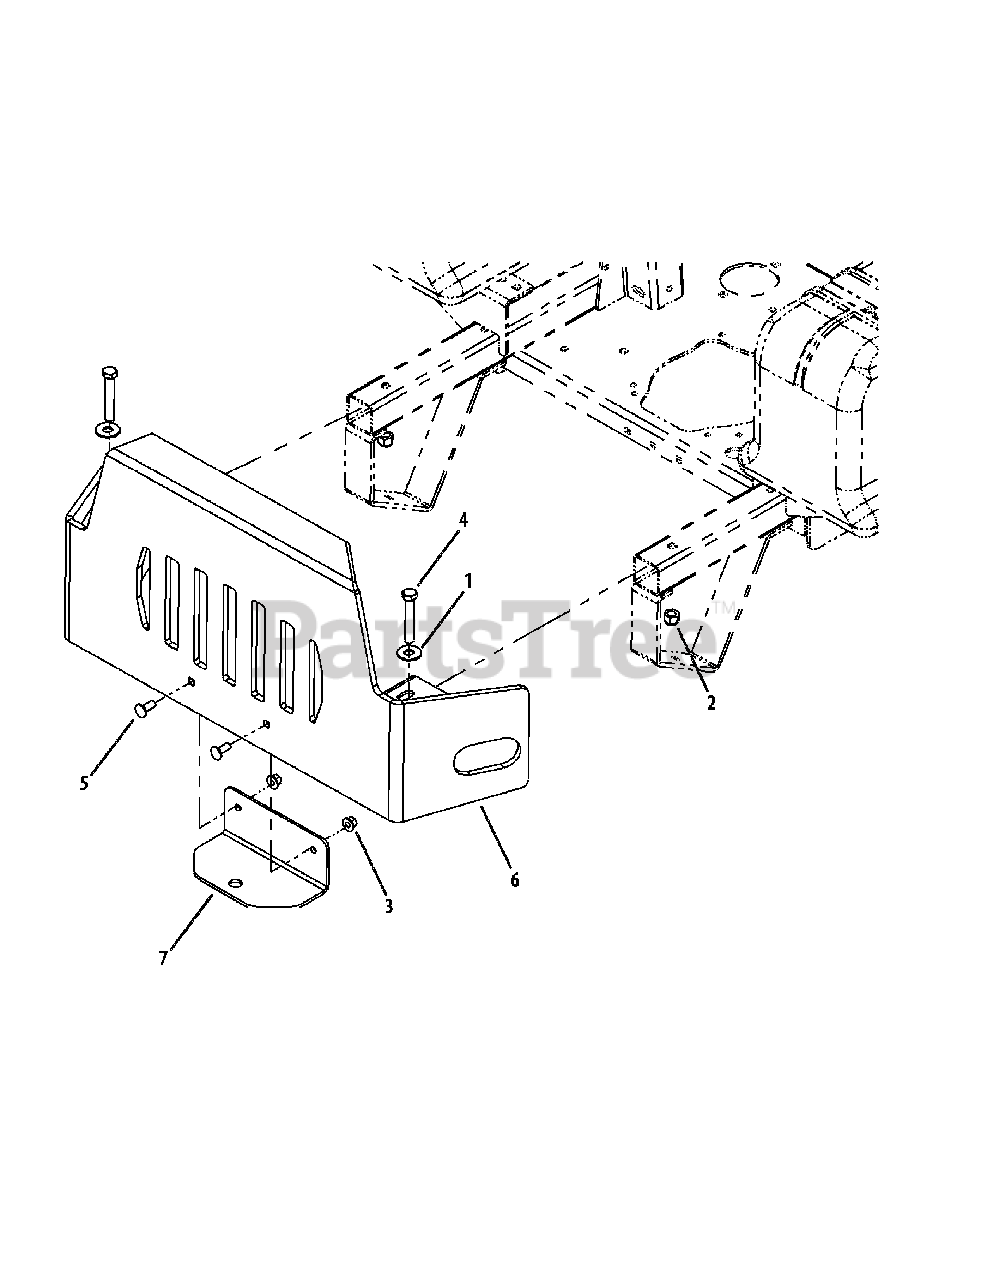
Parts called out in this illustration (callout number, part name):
1	Flat Washer, 1/2
2	Hex Nut, 1/2-13, Insert Lock
3	Nut, Hex 3/8-16 Flange Lock
4	Hex Cap Screw, 1/2-13, 3.00
5	Carriage Bolt, 3/8-16 x 1.00
6	Bumper Assembly
7	Hitch Bracket
